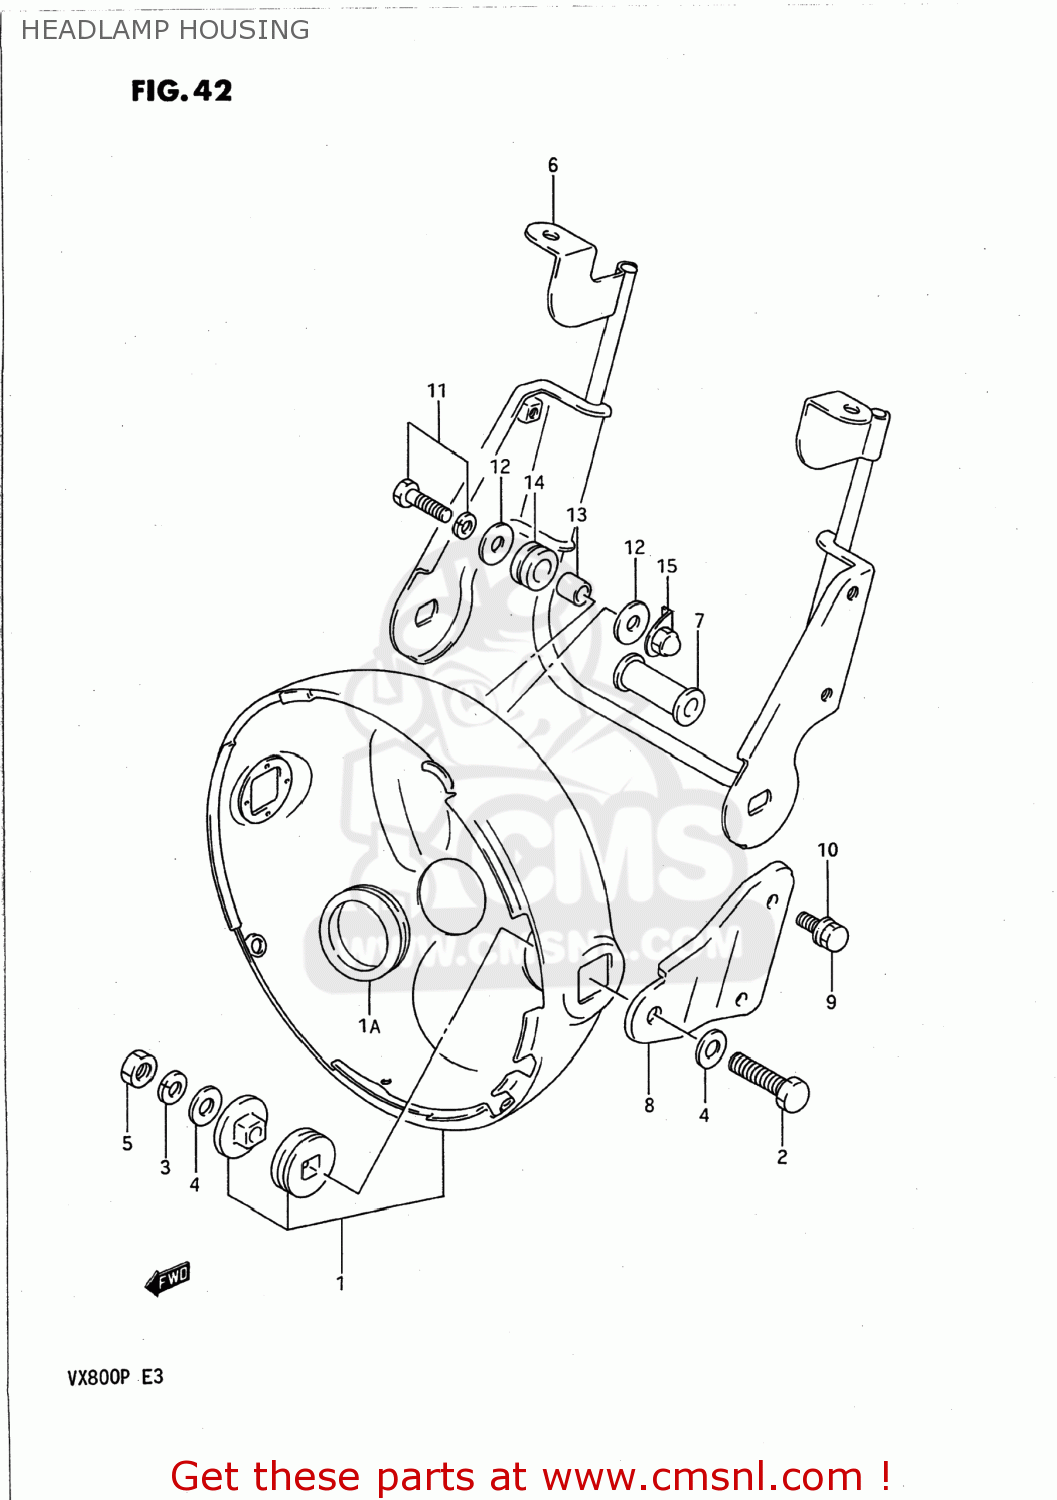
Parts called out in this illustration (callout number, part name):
1	HOUSING,HEADLAMP
1A	GROMMET
2	BOLT
3	LOCK WASHER
4	WASHER
5	NUT
6	BRACKET,HEADLAMP
7	CUSHION
8	STAY,HEADLAMP HOUSING,R
9	BOLT
10	WASHER
11	BOLT
12	WASHER
13	SPACER(6.5X10.5X12)
14	CUSHION
15	PLATE,HEADLAMP
